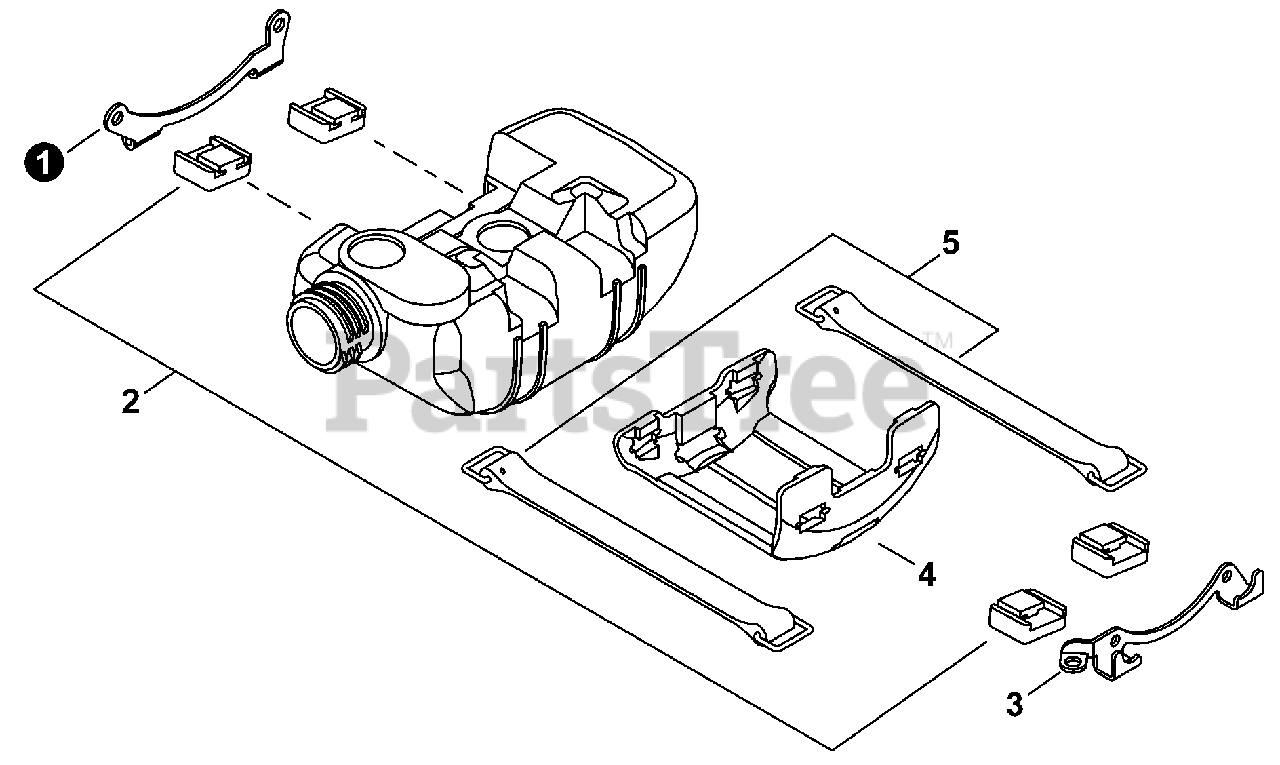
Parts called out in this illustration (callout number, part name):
1	BRACKET M
2	CUSHION, FUEL TANK
3	BRACKET S
4	GUARD, FUEL TANK
5	STRAP, FUEL TANK
